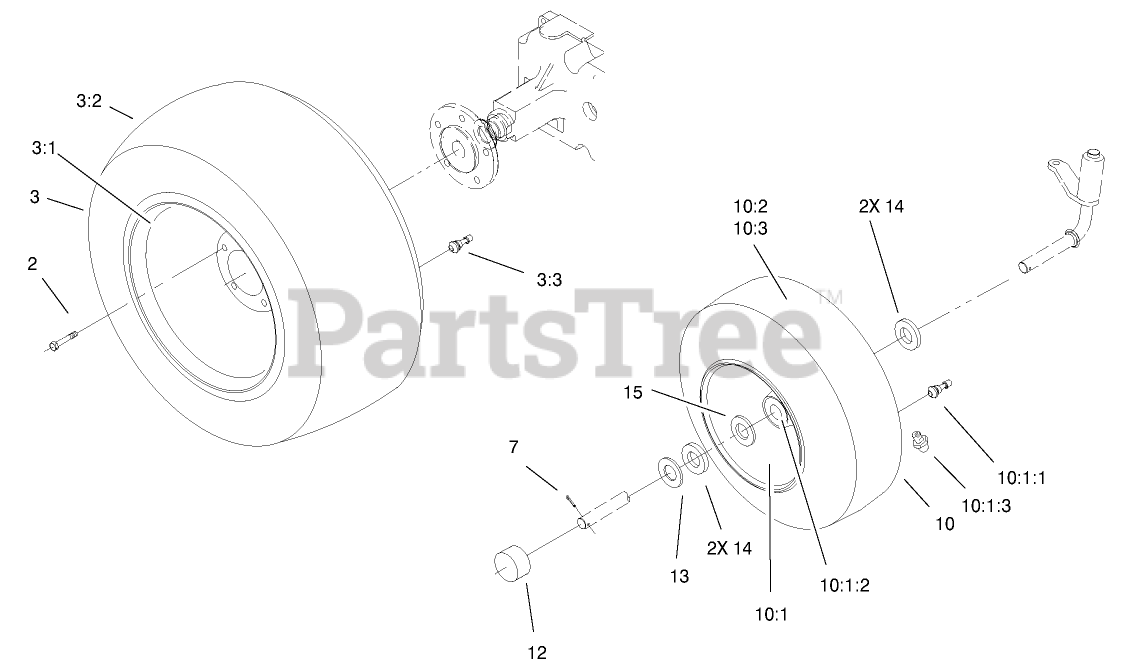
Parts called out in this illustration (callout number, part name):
2	BOLT-LUG
3:1	WHEEL
3:3	VALVE
7	PIN-COTTER
10:1	WHEEL ASM
10:1:1	VALVE
10:1:2	BEARING-WHEEL
10:1:3	ZERK-GREASE
10:2	VALVE
10:2	TIRE-15 X 6.00-6
10:3	TIRE (16 X 6.5-8) 2-PLY -2 WHEEL AXEL
12	CAP-HUB
13	WASHER-PLAIN
14	WASHER
15	WASHER-SHIM
